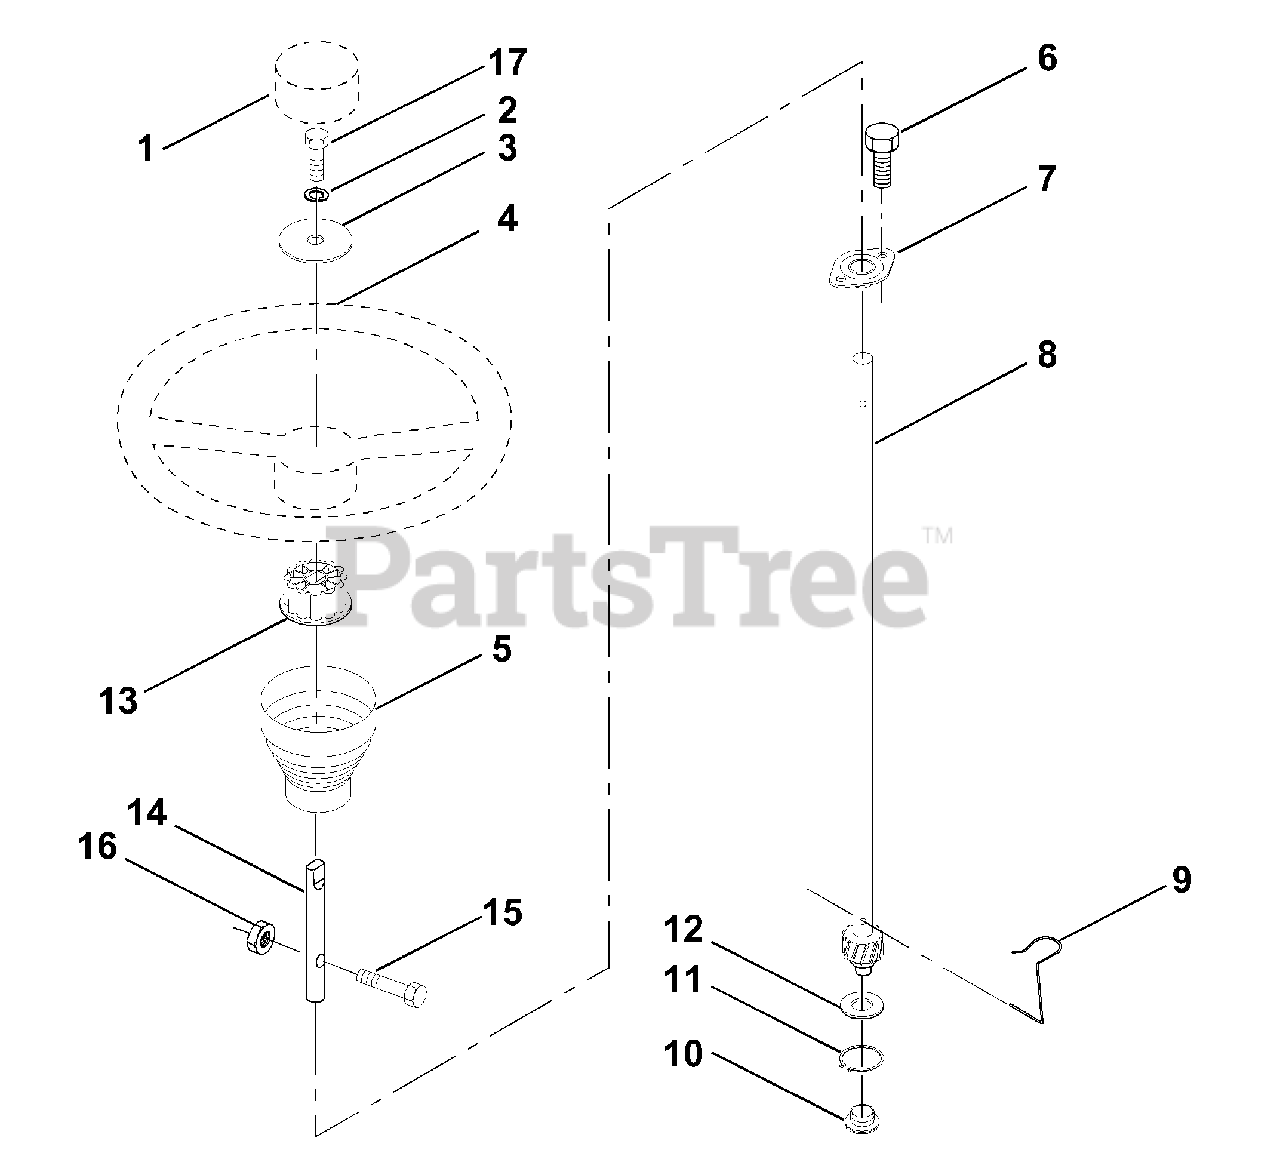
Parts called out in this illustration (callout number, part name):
1	Insert, Wheel, Steering
2	Washer, Lock hvy HLCL SPR 3/8
3	Washer 12/32 x 2-3/8 x 8 Ga.
4	Wheel, Steering
5	Sleeve, Steering
6	Screw, TT #10-32.5.3/8 flange
7	Bushing, Steering
8	Shaft, Steering
9	Clip, Steering
10	Bushing, Lower, Steering
11	Ring, Retaining
12	Washer 21/32 x 1 x 16 Ga.
13	Adaptor, Wheel, Steering
14	Extension shaft steering
15	Bolt Fin Hex 5/16-18 UNC x 1-1/4
16	Nut Lock Hex W/Ins. 5/16-18 UNC
17	Bolt fin Hex 3/8-16 UNC x 1. Gr. 5
